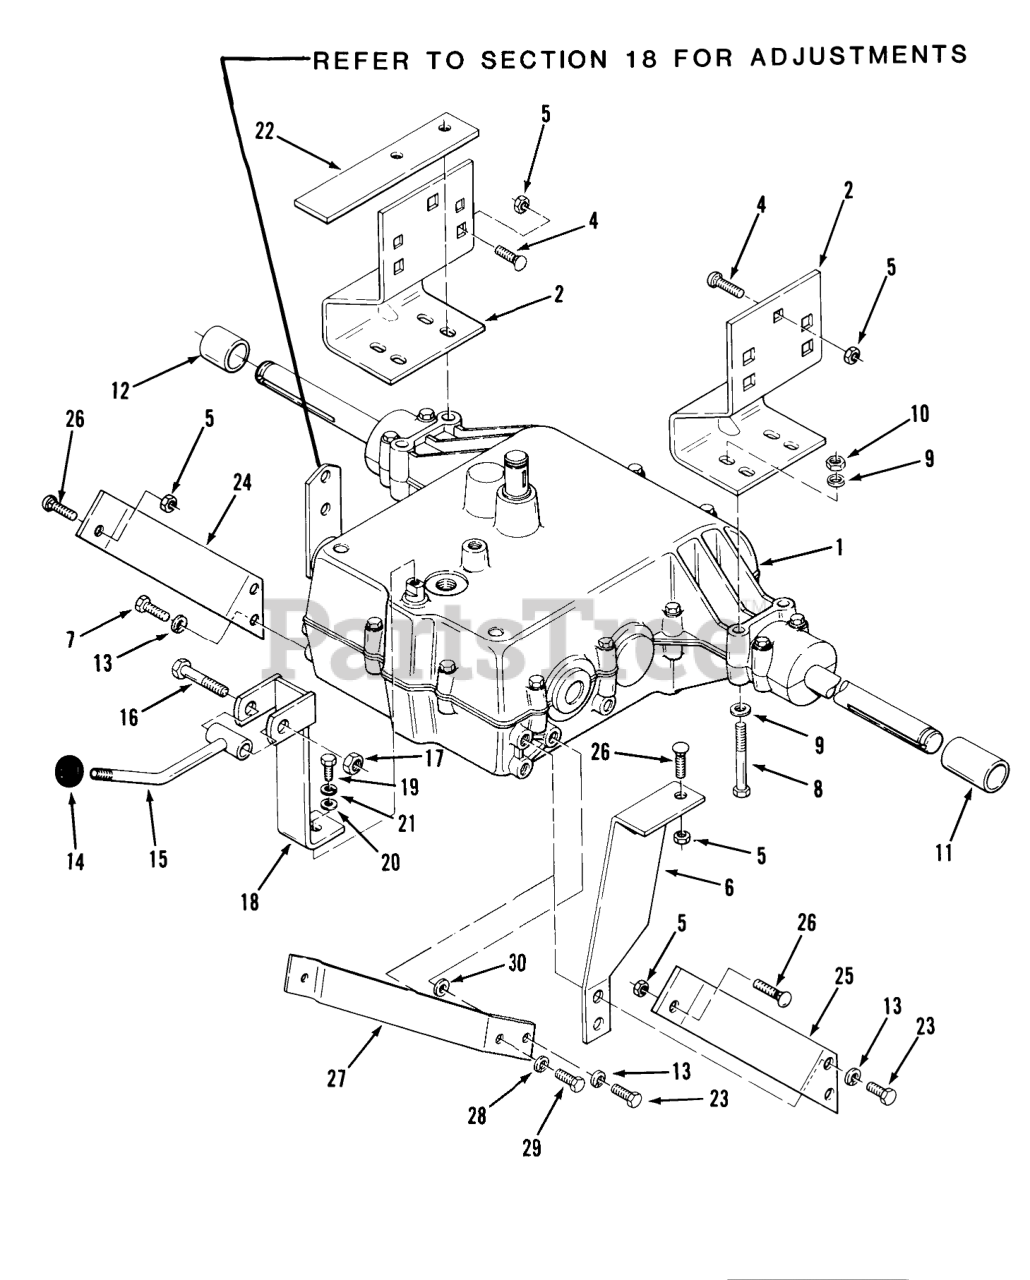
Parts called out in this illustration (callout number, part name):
1	Transmission-Peerless Model 822
1	Transmission-3-Speed Peerless Model 900-003
2	BRKT-TRANS MOUNT R
2	Bracket-Rear Axle RH
2	Bracket-Rear Axle LH-3-Speed Only
4	CARRIAGE BOLT -4
5	Nut
6	TORQUE STRAP
6	Torque Strap 3-Speed Only
7	Screw
8	HHCS
9	WASHER 5/16 SAE
10	Nut
11	SPACER-AXLE LH
11	SPACER
12	SPACER-AXLE RH
13	Lockwasher
15	ASSY-UPPER SHIFT ROD
16	Bolt
17	Nut
18	ASSY LEVER R
18	Shift Lever-Lower 3-Speed Only
19	Bolt 1/4-28 X 7/8
20	WASHER
21	Washer
22	Brake Stop Bar
22	Brake Stop Bar 3-Speed Only
23	Bolt
24	TORQUE STRAP RH
24	TORQUE STRAP RH R
25	TORQUE STRAP LH
26	Bolt
27	TORQUE STRAP LH R
28	Washer
29	Bolt, 1/4-20 x 3/4 Swage Form
